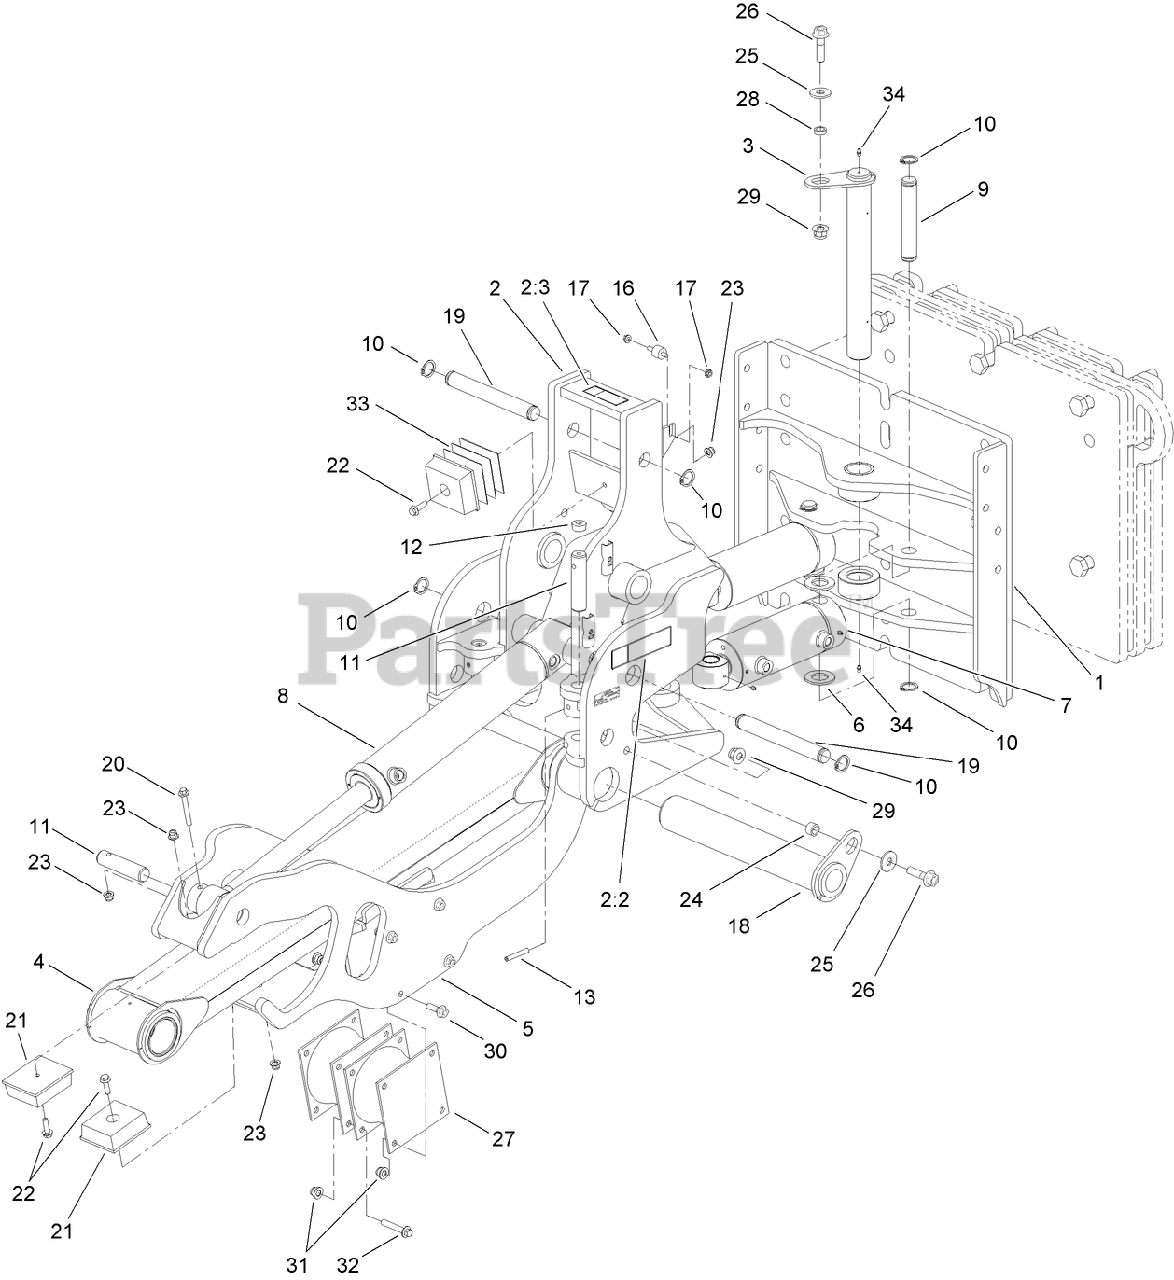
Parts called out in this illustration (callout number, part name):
1	MOUNTING-W PLOW
2	SWING FRAME ASM
2:2	DECAL-DANGER, PLOW
2:3	DECAL-DANGER
3	PIN-FLAGGED
4	ARM-PLOW, LOWER
5	CRADLE-LIFT, PLOW
6	WASHER-FLAT
7	HYD CYLINDER ASM
8	HYD CYLINDER ASM
10	RING-RETAINING, EXTERNAL
11	PIN-ROD
12	PLUG-FREEZE
13	PIN-ROLL
16	MOUNT-RADIATOR
17	NUT-HF
18	PIN-FLAGGED
19	PIN-PLOW
20	SCREW-HHF
21	BUMPER
22	SCREW-HHF
23	NUT-FLANGE, NYLOCK
24	SPACER-PIN
25	WASHER-FLAT
26	SCREW-HHF
27	MOUNT-RUBBER, SHEAR
28	SPACER-PIN
29	NUT-HHF
31	NUT-HHF, LOCK
32	SCREW-HHF
33	SHIM-BUMPER
34	FITTING-GREASE
